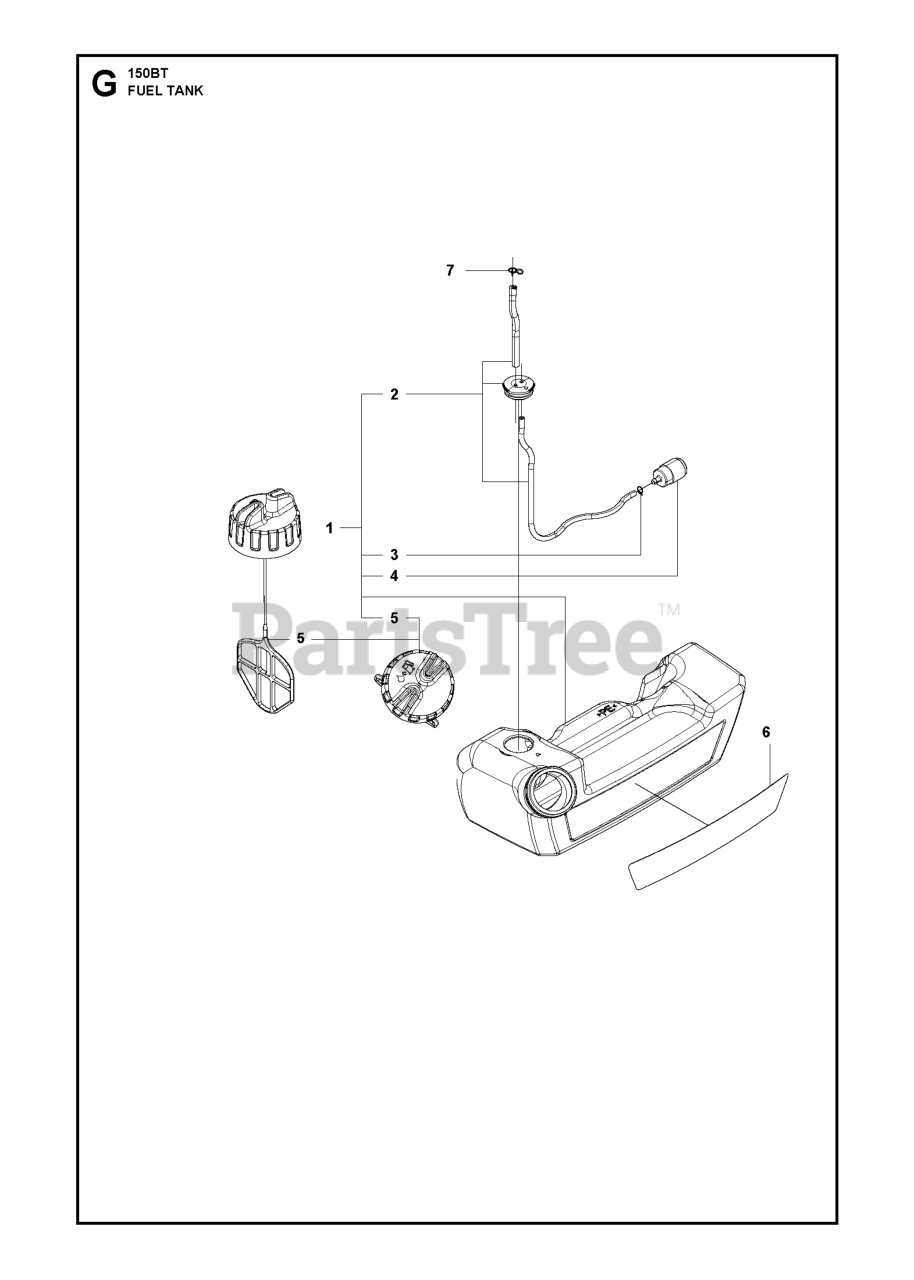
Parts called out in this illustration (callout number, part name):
1	FUEL TANK ASSY
2	Fuel Hoses
4	RP FUEL FILTER
5	FUEL CAP ASSY
